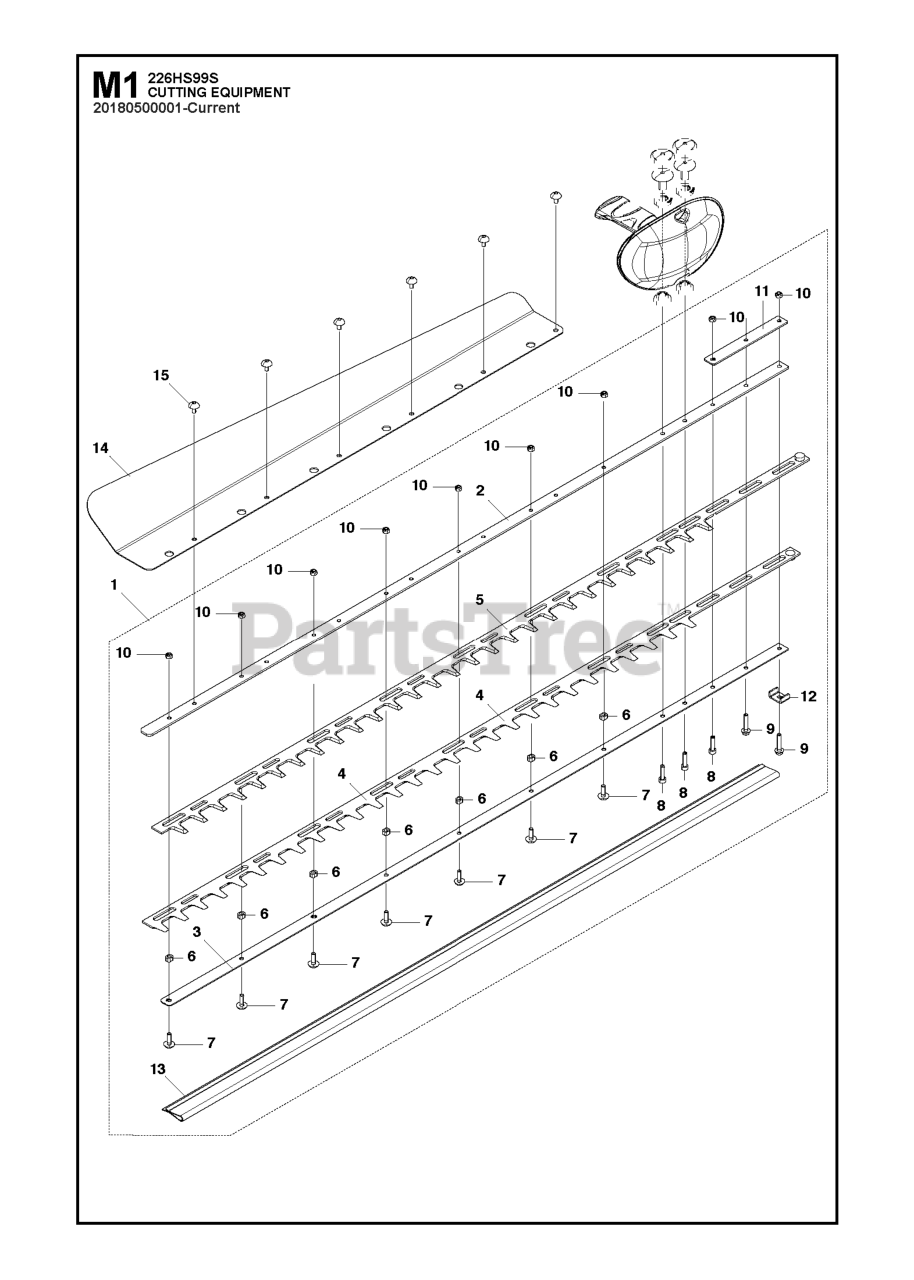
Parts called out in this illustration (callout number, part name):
1	BLADE ASSY 226HS99S
2	PLATE UPPER
3	PLATE LOWER
4	BLADE
5	BLADE
8	BOLT
13	COVER
14	PLATE,RECEIVE
